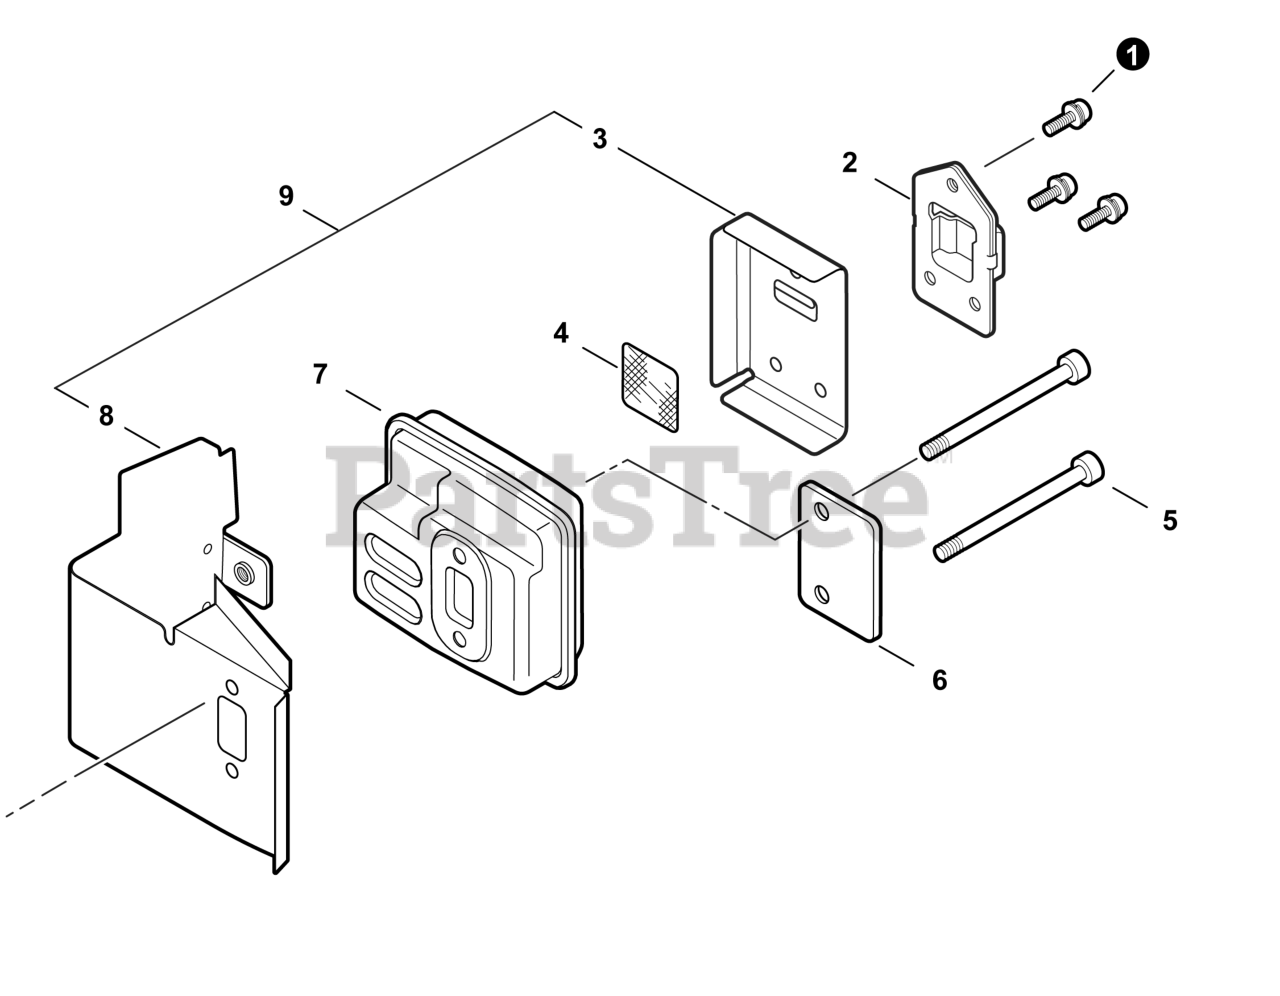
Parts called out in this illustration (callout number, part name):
1	SCREW 4x10
2	GUIDE, EXHAUST
3	GASKET, EXHAUST
4	SCREEN, SPARK ARRESTER
5	BOLT 5x55
6	PLATE, EYE
7	MUFFLER
8	HEAT SHIELD, EXHAUST
9	GASKET KIT: ENGINE, INTAKE, EXHAUST
